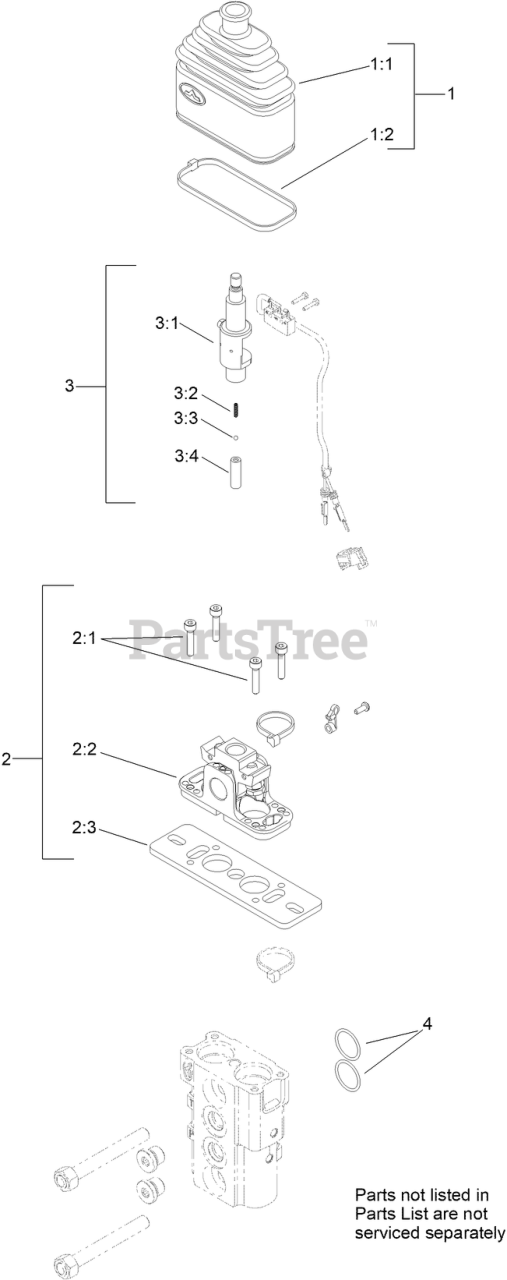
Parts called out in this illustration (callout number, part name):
1	BELLOW KIT
1:1	BELLOW-RUBBER
1:2	HUB and BEARING ASM
2	FULCRUM KIT
2:1	HUB and BEARING ASM
2:2	SUPPORT KIT
2:3	HUB and BEARING ASM
3	SWITCH HOLDER LEVER KIT
3:1	LEVER-HOLDER, SWITCH
3:2	HUB and BEARING ASM
3:3	SPHERE
3:4	HOLDER-SPRING
4	O-RING
